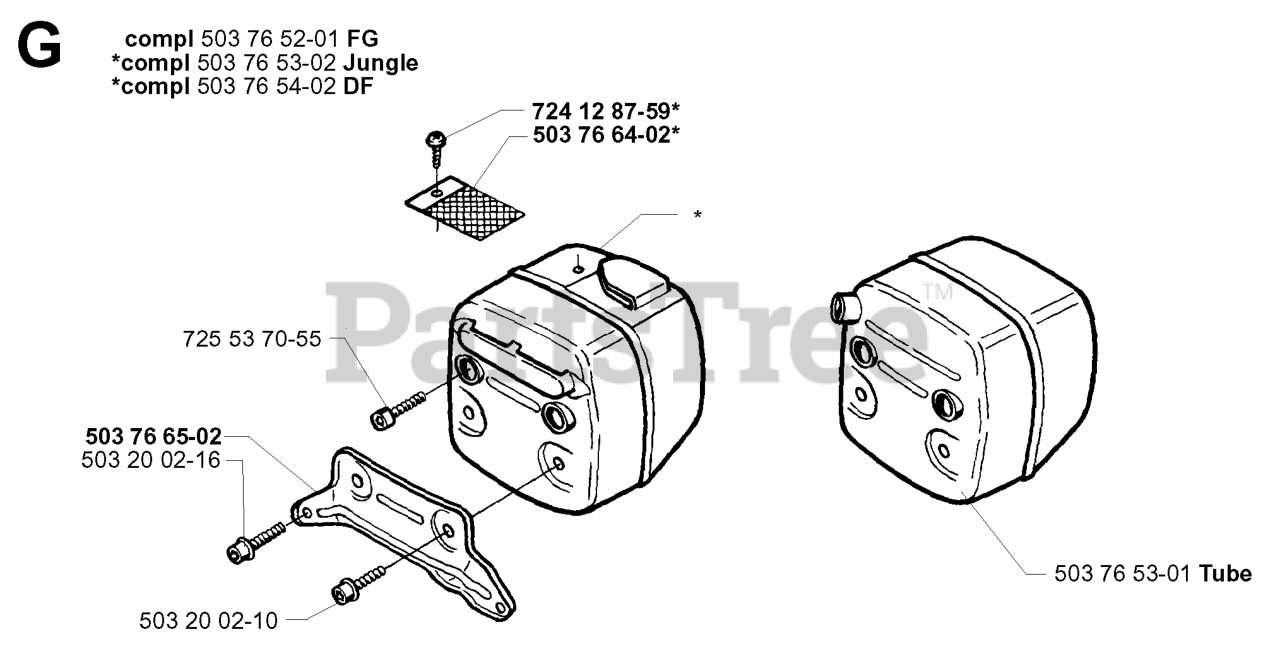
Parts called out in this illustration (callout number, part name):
1	CYLINDR.HEAD.SRV.KIT W/GASKET
2	KIT.PUSH.ROD.SRV(SK208-1001)
3	VALVE COVER ASSEMBLY
5	KIT.PISTON.SRV(SK208-1400)
7	KIT.CAMSHAFT.208CC.LCT
8	FLYWHL.ASSY.ELECT.(SKSN0405)
9	FLYWHEEL FAN 420586
10	CRNKSHFT-KYD#14.208CCSKSNO8001
13	MUFFLER.ASM.LCT.208CC.SNGL.STG
17	CARB.ASM.SS/SNO.LCT(SKSNO313)
18	IGNITION COIL LCT.SKSN0418.1
20	SPARK.PLUG(2083810)
22	SHLD.ELEC.START.FLY(SKSN-0605)
23	KIT.FUEL.HOSE.208CC.SING/STAGE
24	SPEED.CTRL.BRKT.(SKSN0150)
25	GOVENOR.GEARS ASM(SK2082900)
26	CARBURETTOR GOVERNOR LINK.ASM.
27	KIT.GOVERNOR.CRANK(SK208-3100)
28	STARTER.RECOIL.S/S SNO.78".ROP
29	STRTER.CUP(NON-SLOT)SKSN0601.2
30	BLOW.HSG.ASSY.ELEC(SKSN-0602)
31	COVER.CRANKCASE.LCT.HIGH.OIL.F
32	SEAL KIT (2 PCS)
34	SPARK.PLUG.BOOT.SNW,SKSN4691.1
35	STARTER.ASM.ELEC.(SKSNO411)
36	GASKET.KIT.208CC(SK2084300.1)
37	DIPSTICK SMALL
38	ROCKER ARM KIT
40	NON REMOVABLE PLUG
43	TUBE.BREATHER.LCT.208
47	TUBE ASSY HIGH OIL-FILL
48	WIRING HARNESS LCT.SKSN0162.1
49	KIT.OIL.DRAIN.PLUG(SK2089911
51	SHIELD.CYLINGER.LCT.SKSN0608.1
52	BULB.FUEL.PRMR.W/HOSE(SKSNO306
53	SWITH.KEY.ASSEM.SNOW.SINGLE.ST
54	KEY SET(2 KEYS) SKSN0407.1
56	SHIELD.VAPOR.SNOW
62	STARTER.GRIP.SNOW.LCT.SKSN0603
65	TAPPET.KIT.LCT.208CC
69	CARB.STUDS & COUPLING KIT.SNOW
70	CARB.REPAIR.KIT.LCT.SK9900.2
73	SHIELD.INTAKE.(LCT.SKSN0140.1)
77	BOLT.KIT.RECOIL.LCT.ALL.ENGINE
81	KEYS.FLYWHEEL.208/414CC.5PACK
82	SPACER.CARBURETOR.208CC.LCT
86	KIT.BOLT.CYLINDER.HEAD.(4PC)
87	KIT.BOLT.CRANKCASE.COVER.6PC
88	STUD.MUFFLER.KIT.LCT
91	COVER CRANKCASE GASKET
